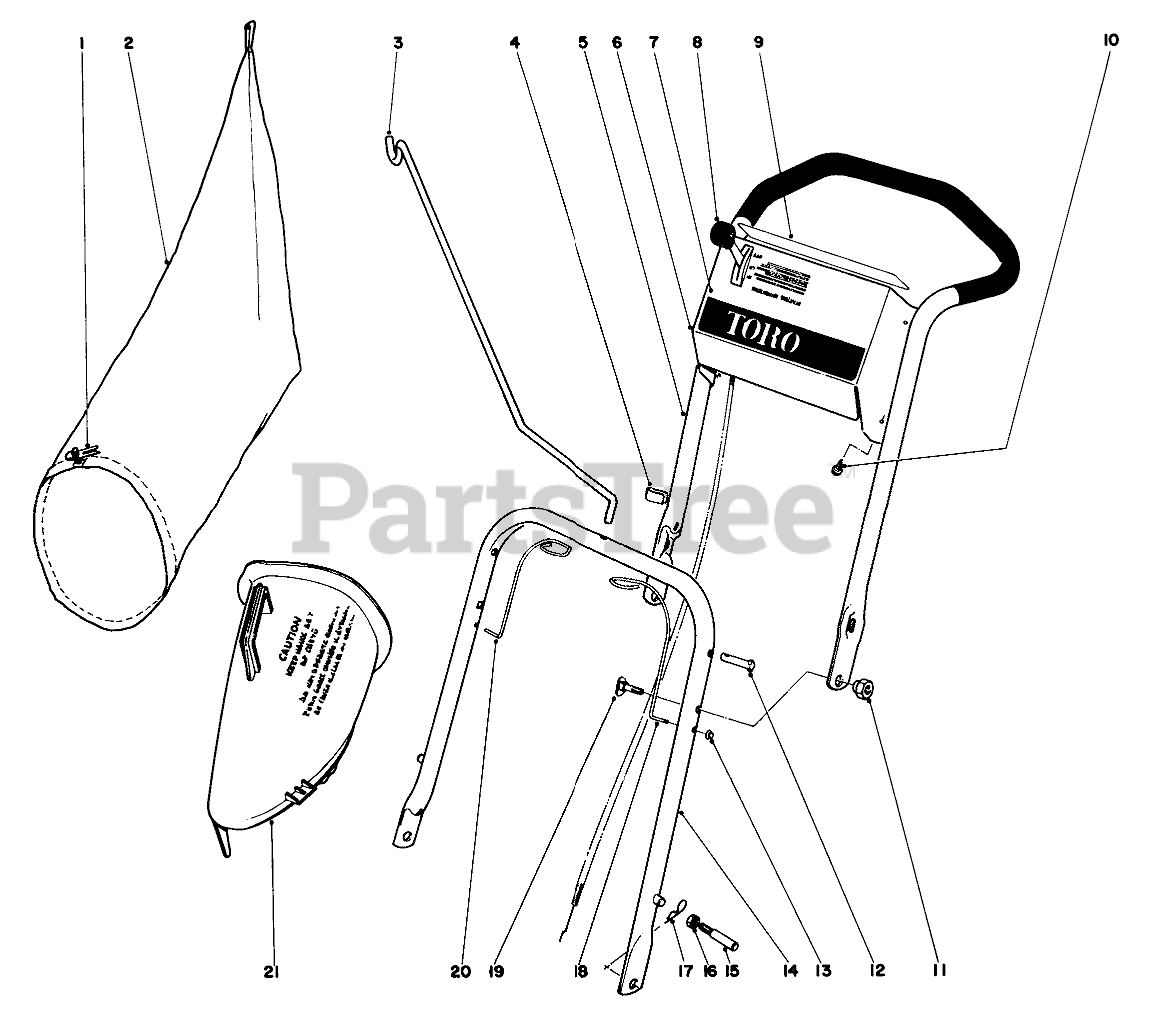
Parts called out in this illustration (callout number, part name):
1	BAG CORD FASTENER
2	Grass Bag (Incl. Ref. #1)
3	Bag Hanger Rod
4	BOWDEN CLIP
5	Upper Handle
6	Control Plate
7	Decal, Control Plate
8	Throttle Control
9	Decal, Safety
10	SCREW-HWHTF
11	Pivot Nut
12	Latch Pin
14	Lower Handle
15	Handle Pin
16	Nut
17	PIN-COTTER, HAIR
18	Latch Spring L.H.
19	HANDLE SCREW
20	Latch Spring R.H.
21	BAG ATTACHMENT
